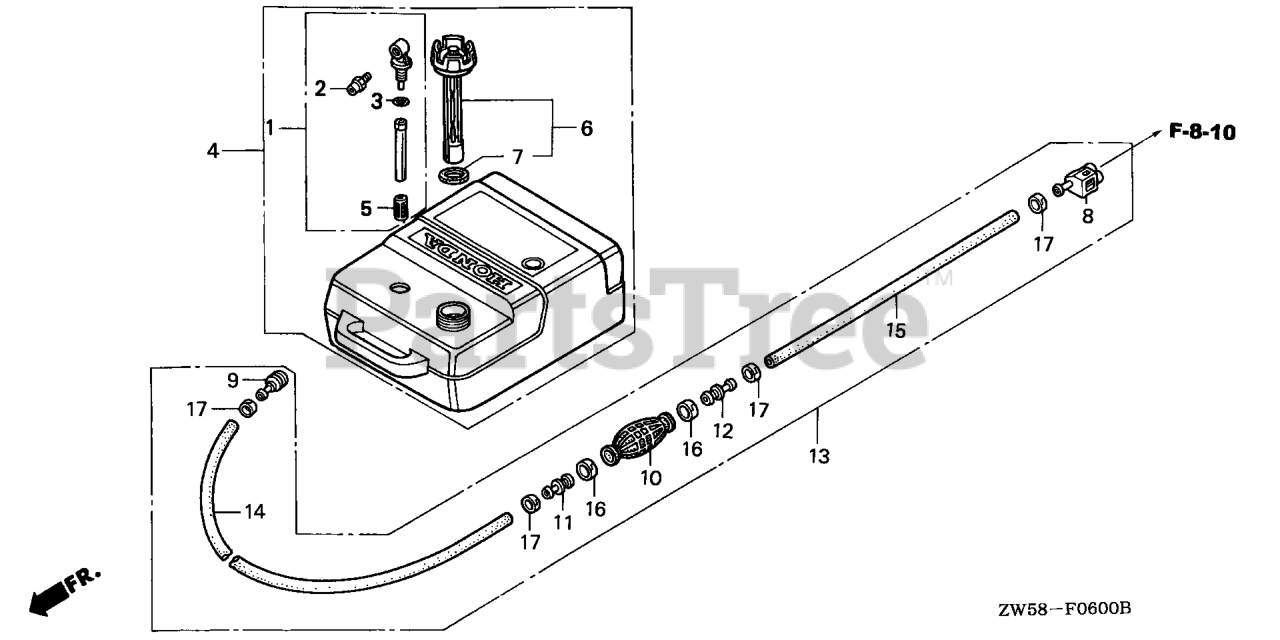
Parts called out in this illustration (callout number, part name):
1	JOINT ASSY., FUEL Use from Frame SN 1300962.
2	FITTING, QUICK DISCONNECT Use from Frame SN 1205705.
3	O-RING Use from Frame SN 1300962.
4	TANK ASSY., FUEL
5	FILTER, FUEL
6	CAP, FUEL FILLER
7	GASKET, FUEL CAP
8	CONNECTOR ASSY., FUEL (A)
9	CONNECTOR, FUEL (CONNECTOR TYPE)
10	BULB, PRIMER
11	VALVE, IN.
12	VALVE, OUTLET
13	TUBE ASSY., FUEL
14	TUBE, FUEL LONG (7.3X2000) (CONNECTOR TYPE)
15	TUBE, FUEL SHORT (6.3X500) (CONNECTOR TYPE)
16	BAND, TUBE CLIP (20MM)
17	BAND, TUBE CLIP (12.5MM)
